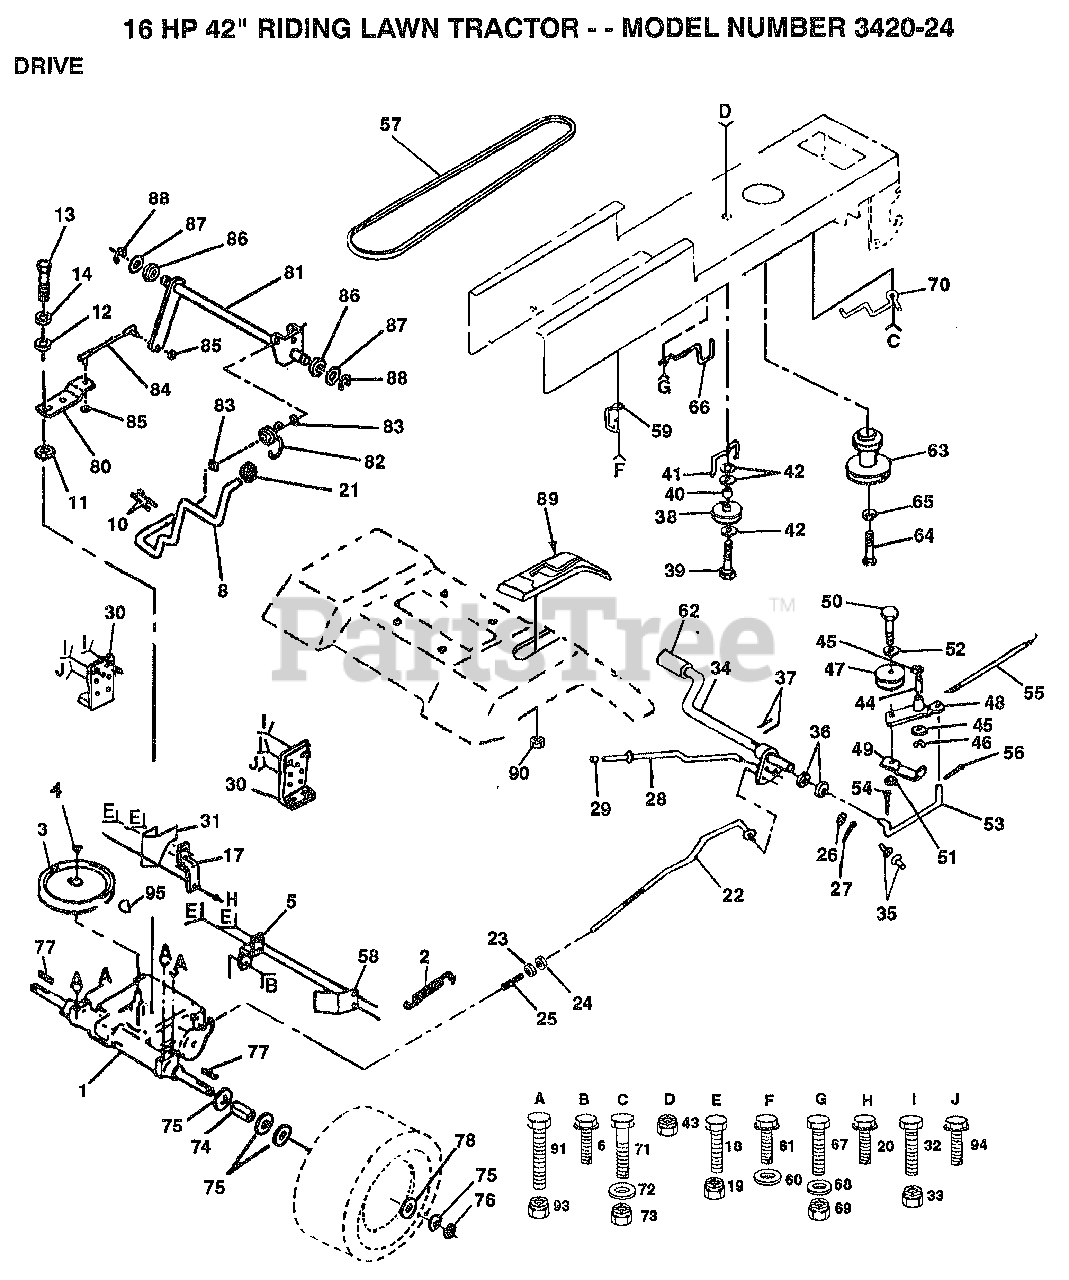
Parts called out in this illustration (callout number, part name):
3	"PULLEY,TRANSAXLE"
6	SCREW
10	PIN COTTER 1/8
11	WASH-SHFT PLT LT
12	WASHER
14	LOCKWASHER
17	STRAP TORQUE
20	SCREW
21	KNOB T (1/2-HOLE)
22	BRAKE ROD
23	NUT
24	NUT
25	SPRING ROD LT
26	WASHER
27	COTTER PIN
28	BRAKE PARK ROD
29	PLUNGER CAP T
30	TRANSAXLE MTG BKT
31	"KEEPER,BELT LH"
32	BOLT
35	NYLON BEARING
36	WASHER LT
38	PULLEY.IDLER.FLAT
39	BOLT
40	SPACER T
41	BELT KEEPER LT
42	WASHER
44	"LY, BEARING"
45	WASHER LT
46	KLIP RING
48	ARM IDLER
49	RETAIN BELT
52	WASHER HYT
53	"LINK, CLUTCH T"
54	COTTER PIN
55	"SPRING, RETURN LT"
56	COTTER PIN
57	BELT-V
58	"KEEPER,BELT RH"
60	WASHER
61	SCREW
62	PEDAL COVER T
64	BOLT
65	LOCKWASHER
66	KEEPER.BELT.ENG.L
67	BOLT
68	WASHER
70	KEEPER BELT ENG
71	BOLT
72	WASHER
74	SPACER LT
76	E-RING LT
77	SQUARE KEY
78	WASHER
80	ARM SHIFT TRANS
82	"SPRING,TORSION"
83	WASHER
84	TIE ROD
85	NUT 1/4-28
86	"BUSH,PIVOT T"
87	"WSHER,SHIM"
88	RING T
90	NUT
91	BOLT
94	SCREW
